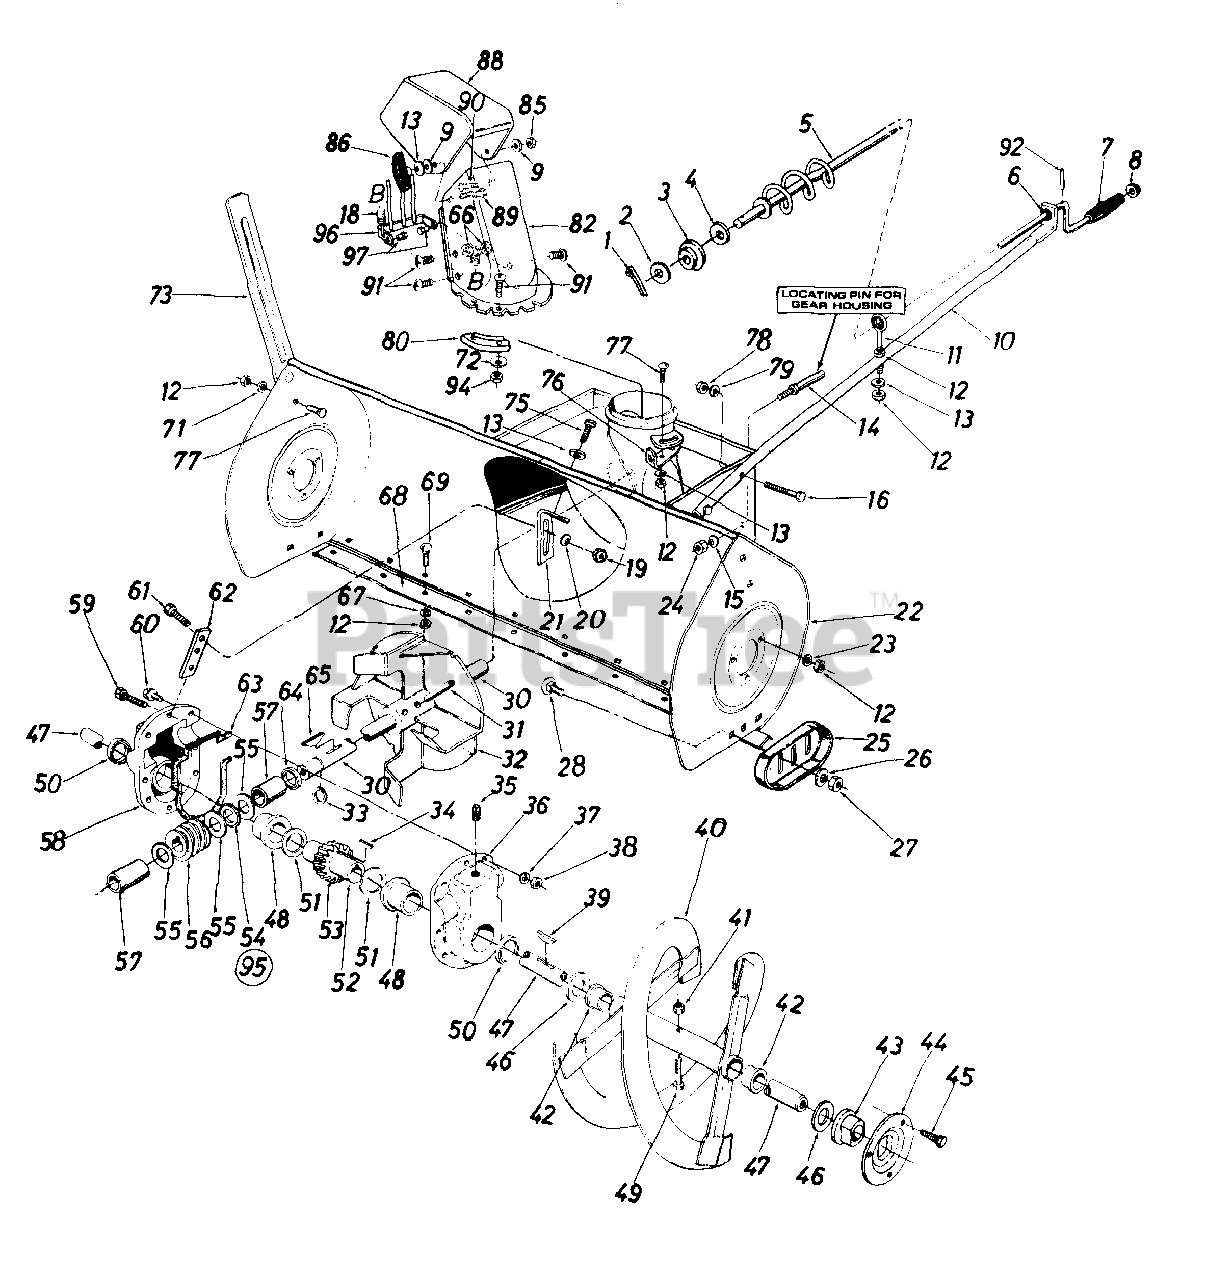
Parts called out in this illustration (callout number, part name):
2	Fl.-Wash. .39" I.D. x .62" O.D.
3	Plastic Bushing
4	Fl.-Wash. .385" I.D. x .62" O.D.
5	Chute Crank Ass'y.
6	Plastic Bushing
7	Knob (Black)
8	Push Nut 3/8" Rod
9	Fl.-Wash. .344" I.D. x 1.25" O.D.
10	Chute Crank Support Tubing
12	Hex Nut 5/16-18 Thd.
13	Bell.-Wash. .345" I.D. x .88" O.D.
14	Stud 3/8-16 x 2.75" Lg.
15	Bell.-Wash. .400" I.D. x .88" O.D.
16	Hex Bolt 3/8-24 x 1.25" Lg.
18	Extension Spring
19	Hex Nut 1/4-28 Thd.
20	Bell.-Wash. .265" I.D. x .75" O.D.
22	45" Snow Blower Housing Ass'y.
23	L.-Wash, 5/16" I.D.
24	Hex Jam Nut 3/8-16 Thd.
25	Slide Shoe
26	Bell.-Wash. .400" I.D. x .88" O.D.
27	Hex Jam Nut 3/8-16 Thd.
28	Carriage Bolt 3/8-16 x .62" Lg.
30	Blower Axle .875" Dia. x 14.75" Lg.
31	Spring Pin Spir. 5/16" Dia. x 1.75" Lg.
34	491 Woodr-Key 1/4 x 3/4" Dia. (HDN)
36	Gear Hsg. Half L.H.
37	Spr.-Wash. .32" I.D. x .62" O.D.
38	Hex Ins. L.-Nut 5/16-18 Thd.
39	491 Woodr-Key 1/4 x 3/4" Dia. (HDN)
41	Hex Ins. L.-Nut 5/16-18 Thd.
42	Plastic Bushing
43	Flange Brg. w/flats 1" I.D.
44	Bearing Housing
45	Hex Sems Bolt 5/16-18 x .75" Lg.
46	Fl.-Wash. 1.00" I.D. x 1.75" O.D.
48	Flange Bearing 1.503" I.D.
49	Shear Bolt 5/16 18 x 1.75" Lg.
50	Oil Seal 1.50" I.D.
51	Fl.-Wash. 1.50" I.D. x 2.00" O.D.
52	Worm Gear Shaft
53	Double Threaded Worm Gear - L.H.
54	Thrust Brg. - .88" I.D. x 1.44" O.D.
55	Fl.-Wash. .88" I.D. x 1.4" O.D
56	Double Threaded Worm - L.H.
57	Sleeve
58	Gear Hsg. Half - R.H.
59	Hex Bolt 5/16-18 x 1.25" Lg.
60	Hex Bolt 5/16-18 x 1.0" Lg (Grade 5)
61	Hex Bolt 1/4-28 x 75" Lg
62	Gear Housing Support Plate
63	Rubber Gasket
64	Oil Seal - .875" I.D.
65	#9 Hi-Pro Key 3/16 x 3/4" Dia. (HT)
66	Hex L-Nut 1/4-20 Thd.
67	L.-Wash. 5/16" I.D.
69	Carriage Bolt 5/16-18 x 1.00" Lg.
71	L-Wash. 5/16" I.D.
72	Fl.-Wash. 1/4" I.D.
73	Guide Blade
75	Hex Wash. Hd. AB Tap Scr. 5/16" x .75" Lg.
77	Carriage Bolt 5/16-18 x,75" Lg.
78	Hex Ins. L.-Nut 3/8-24 Thd.
79	L.-Wash. 3/8" I.D.
80	Chute Flange Keeper
82	Lower Chute
85	Hex Cent. L.-Nut 5/16-18 Thd.
86	Knob Handle
88	Upper Chute
89	Carriage Bolt 5/16-18 x 1.00" Lg.
90	Truss Mach. Scr. 5/16-18 x .75" Lg.
91	Truss Mach. Scr. 1/4-20 x .75"
92	Roll Pin .12" Dia. x .63"
94	Hex Cent. L-Nut 1/4-20 Thd.
95	Gear Box Ass'y.-Comp.
97	Shld. Nut 1/4-20 Thd.
